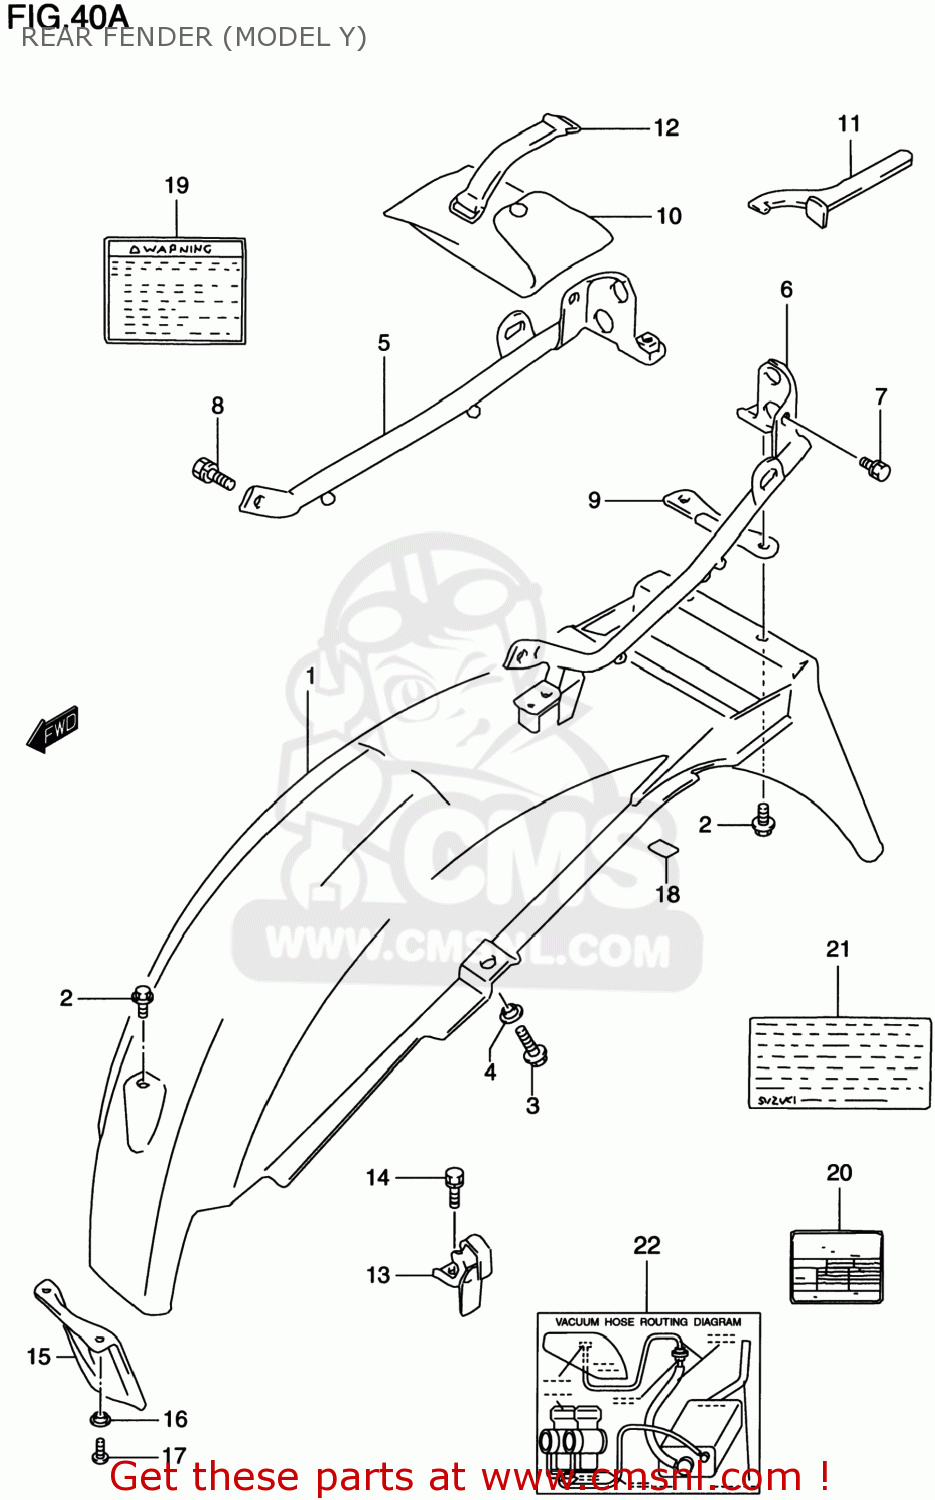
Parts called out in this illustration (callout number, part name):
1	BODY,REAR FENDER
2	BOLT(6X16)
3	BOLT
4	WASHER
5	BRACE,RR FENDER,R
6	BRACE,RR FENDER,L
7	BOLT
8	BOLT
9	PLATE,TOOL HOLDER
10	TOOL ASSY
11	CLAMP
12	BAND
13	HOLDER,HELMET
14	BOLT
15	GUARD,RR UNIT MUD
16	WASHER
17	SCREW
18	TAPE,RR FENDER
19	LABEL,GENERAL WARNING
20	LABEL, TIRE INFORMATION
21	LABEL (MANUAL NOTICE)
22	LABEL (VACUUM HOSE ROUTING)
23	MANUAL,OWNER'S GS500EY
